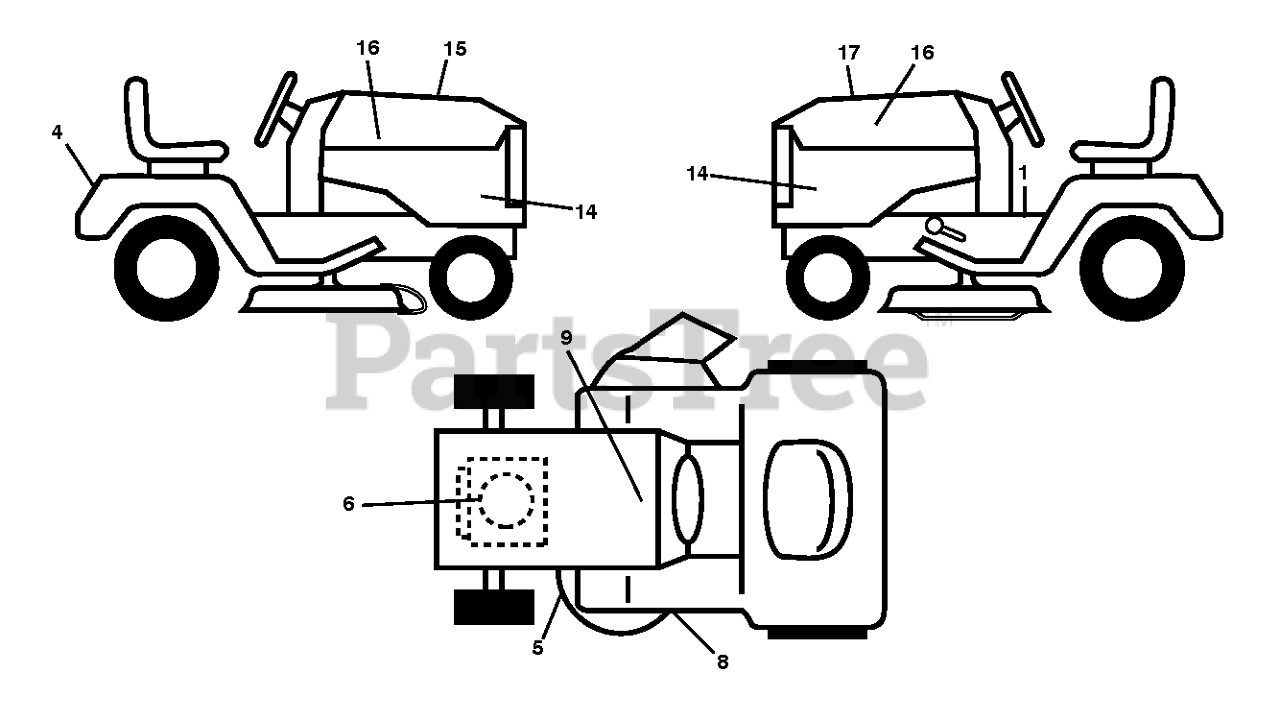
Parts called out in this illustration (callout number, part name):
1	DECAL.WARN.START.INSTRUCTIONS
4	DECAL.FENDER
5	DECAL.MOWER
6	DECAL.ENG.BS.23HP.XRD.TWIN
8	DECAL.MOWER.SCH.48/54
9	DECAL BTRY SYMBOLS
14	DECAL.SDPNL.HUSGT2.YTH2348.HUS
15	DECAL.WARNING.CUST.RESP.E85.
16	DECAL.BADGE.170MM.TEXTLOGO.
17	DECAL.RPL.BSM44.INTK.TLW.48.K4
